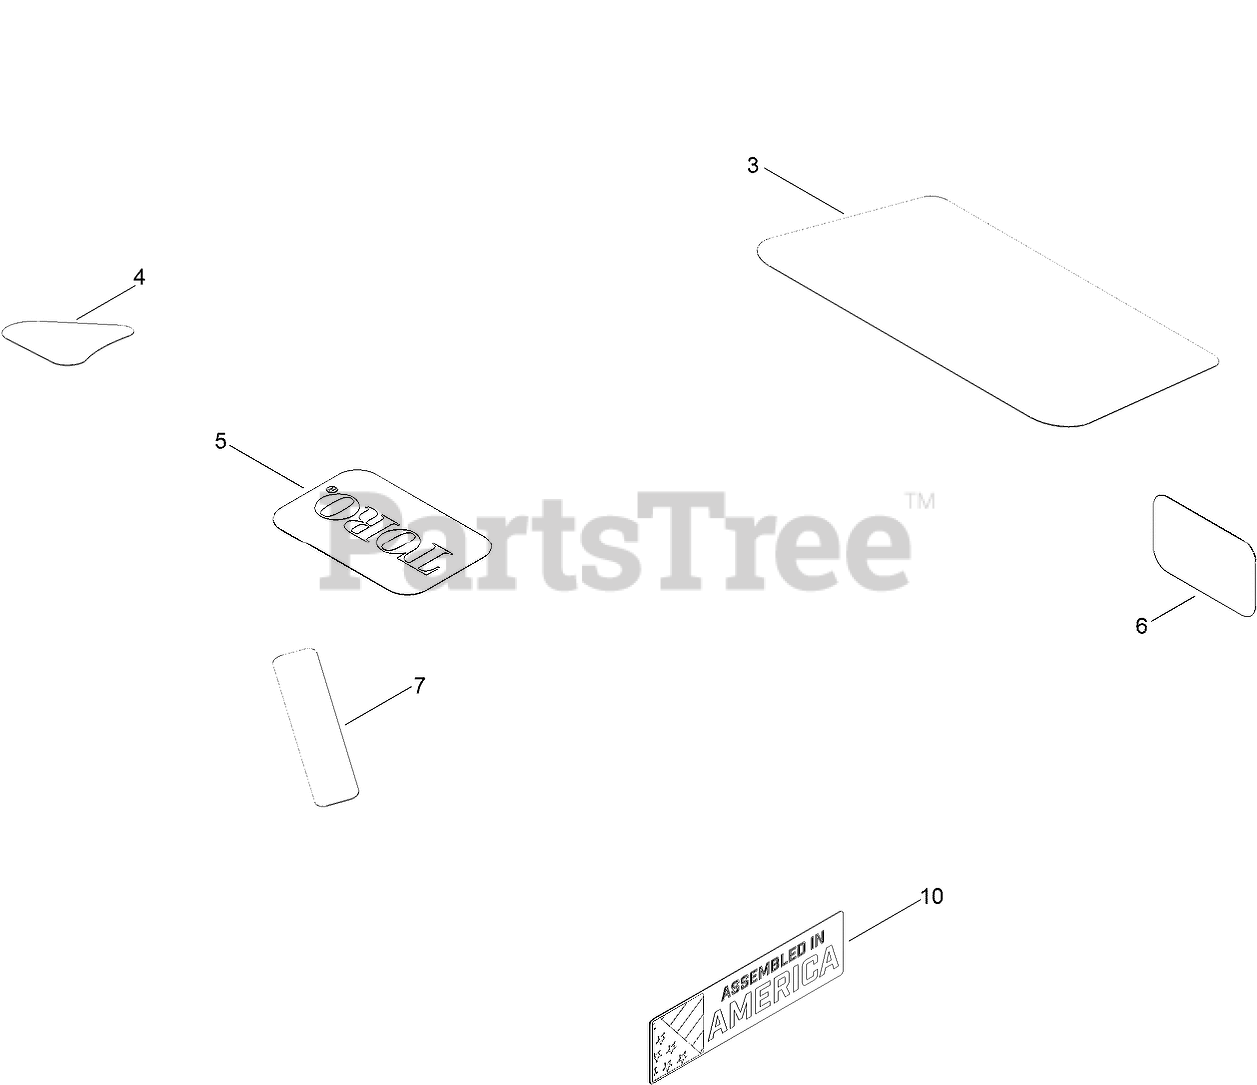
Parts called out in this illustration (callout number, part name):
3	DECAL-ENGINE
4	DECAL-DRAIN, OIL
6	PLACARD-INTAKE
7	DECAL-SHUTDOWN
